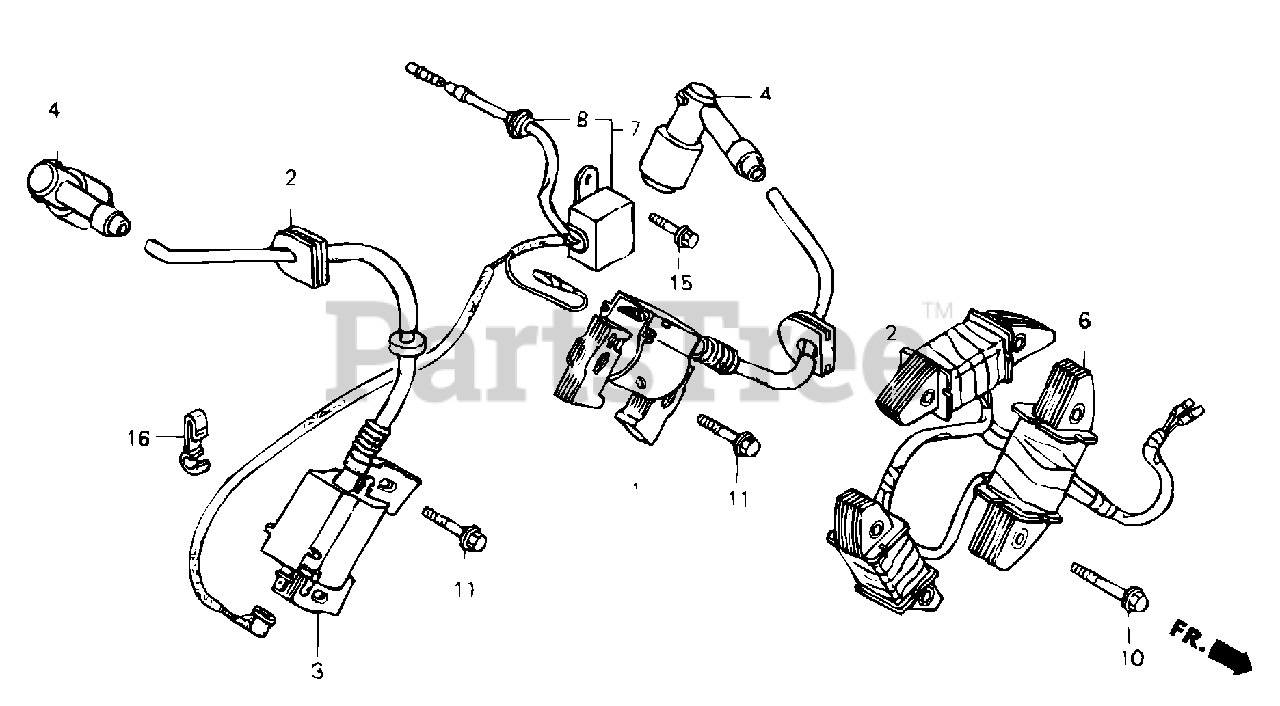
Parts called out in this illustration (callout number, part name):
1	Coil Assembly., R. Ignition
2	Grommet, Ignition Wire
3	Coil Assembly., L. Ignition
4	Cap Assembly., Noise Suppressor
6	Coil Assembly., Charge (12V/20A)
7	Diode Assembly., Engine Stop
8	Grommet, Tool
10	Bolt, Flange (6x32)
11	Bolt, Flange (6x32)
15	Bolt, Flange (6x8)
16	Clamp, Wire
